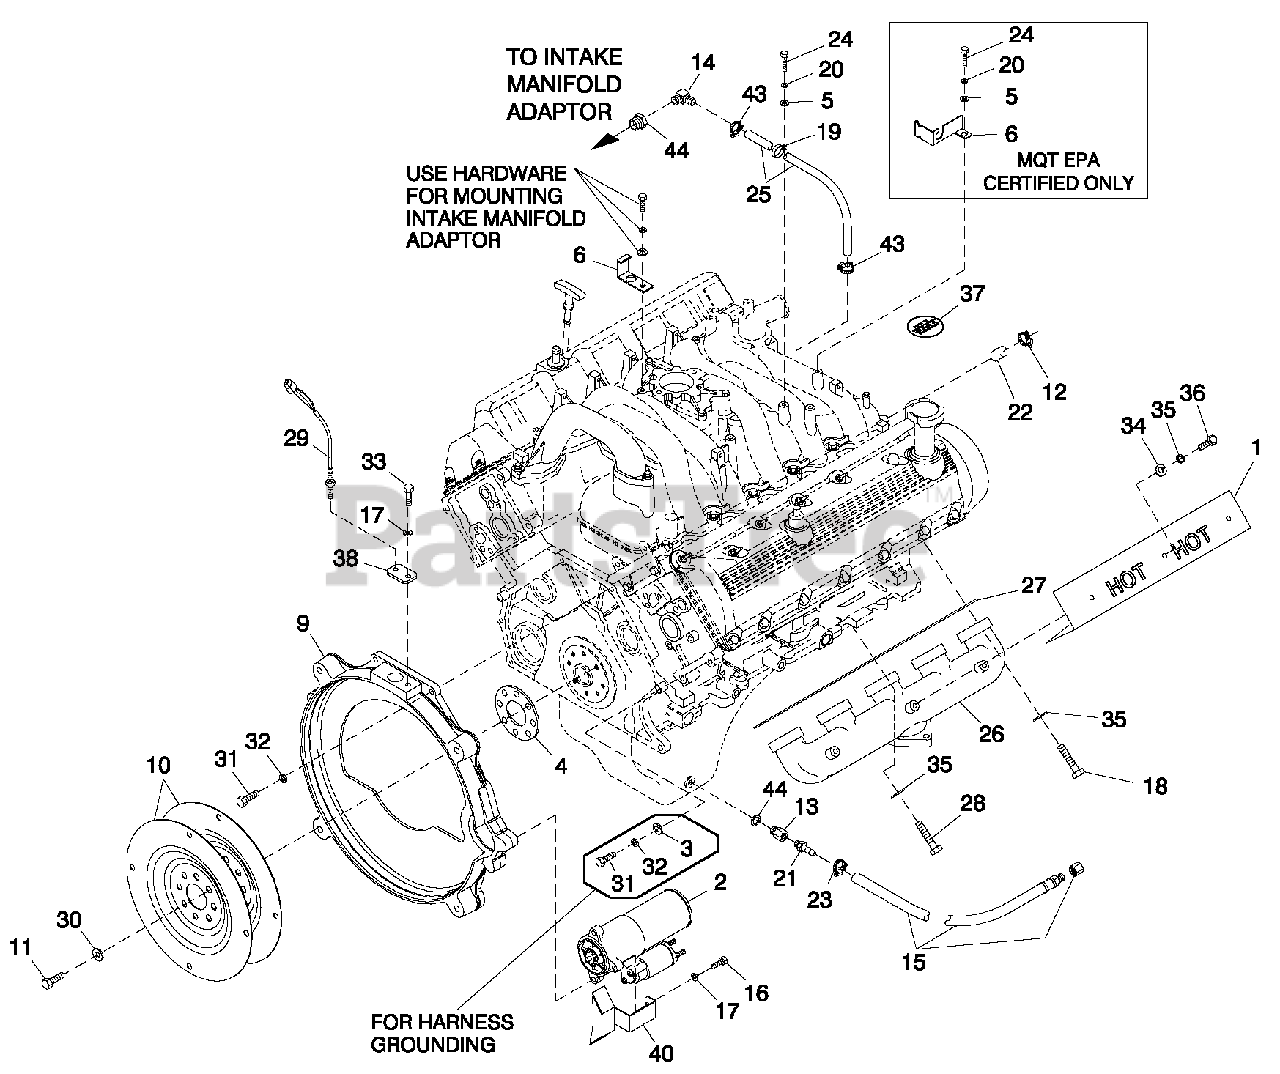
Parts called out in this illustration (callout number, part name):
1	HEAT SHIELD EXHAUST
2	STARTER MOTOR FORD V-10 ENGINE
3	WASHER FLAT3/8-M10ZINC
4	SPACER FLEXPLATE5.4L/6.8L(1800 RPMUNITS ONLY)
5	WASHER FLAT 1/4-M6ZINC
6	BRACKET SIGNAL CONDITIONER
7	TIE WRAP UL7.4" X .19" BLK
8	WASHER NYLON .565
9	ENGINE ADA PTER54L/6.8L
10	FLEXPLATE 2 POLE (1800 RPM UNITS ONLY)
11	SCREW HHCM10-1.0X 25 G10.9
12	CLAM PHOSE #10.56 -1.06 (1800 RPM UNITSONLY)
13	ADAPTERM14-1.50 X3/8NPT
14	BARBED EL 90 3/8NPTX5/8
15	HOSE DRAIN ASSY 28"
16	SCREW HHCM8-1.25X 30 G8.8
17	WASHER LOCK M8-5/16
18	SCREW SHC M8-1.25X35SS
19	CLAMP VINYL .75X.343Z
20	WASHER LOCK M6-1/4
21	BARBED STR 3/8NPTX3/8
22	CAP HOSE (1800 R PM UNITS ONLY)
23	CLAM PHOSE .38-.87
24	SCREWHHCM6-1.0 X16G8.8
25	HOSE COOL 5/8" ID 250#W P (14" )
26	EXH MAN FOLD MACH 6.8L V-10
27	GASKET EXHAUST MANIFOLD
28	SCREW HHCM8-1.25X 35 SSG8.8
29	ASSY MAGPICK U P (3/8-24 MALE)
30	WASHER FLAT.43 X1.00
31	SCREW SHC M10-1.5X 25 G12.9
32	WASHER LOCK M10
33	SCREW HHCM8-1.25X 20 G8.8
34	WASHER FLATM8 SS
35	WASHER LOCK M8SSTL
36	SCREW HHC 916-18X 1/2 SSTL
37	DECAL REFER TO OWNERS MANUAL
38	PLATE MAGPICK-UPADAPTOR
40	COVER STARTER 5l4 & 6.8 FORD CPL
43	CLAM PHOSE #10.56-1.06
44	ADAPTOR 1/4' NPT TO 3/8" NPT
